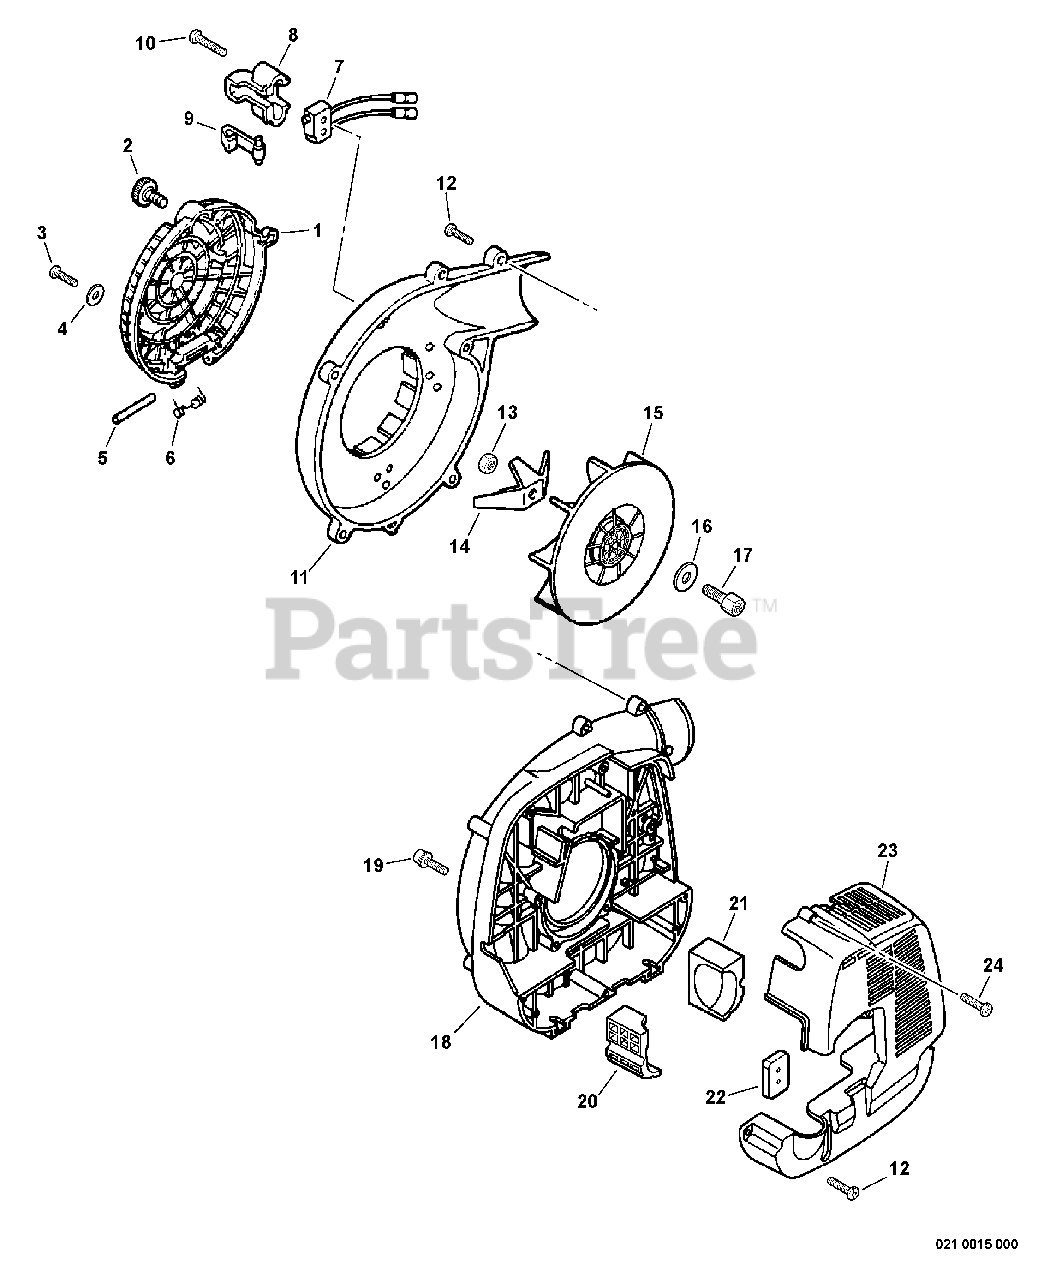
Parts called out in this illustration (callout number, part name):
1	GUARD, DEBRIS
2	THUMBSCREW
3	SCREW - 5X14
4	WASHER - 5
7	IGNITION SWITCH ASSY
8	BRACKET, SWITCH - GRAY
9	LEVER, SHUT OFF ACTUATOR
10	SCREW - 4X22
11	COVER, FAN - LEFT
12	SCREW - 5X20 -- TAPPING
14	BLADE, SHREDDER
16	WASHER - 8
17	HUB, FAN
18	COVER, FAN - RIGHT
19	SCREW - 5X20
20	CUSHION, FUEL TANK - LEFT
21	CUSHION, FUEL TANK - RIGHT
22	CUSHION, FUEL TANK - FRONT
23	COVER, ENGINE
24	SCREW - 5X20
